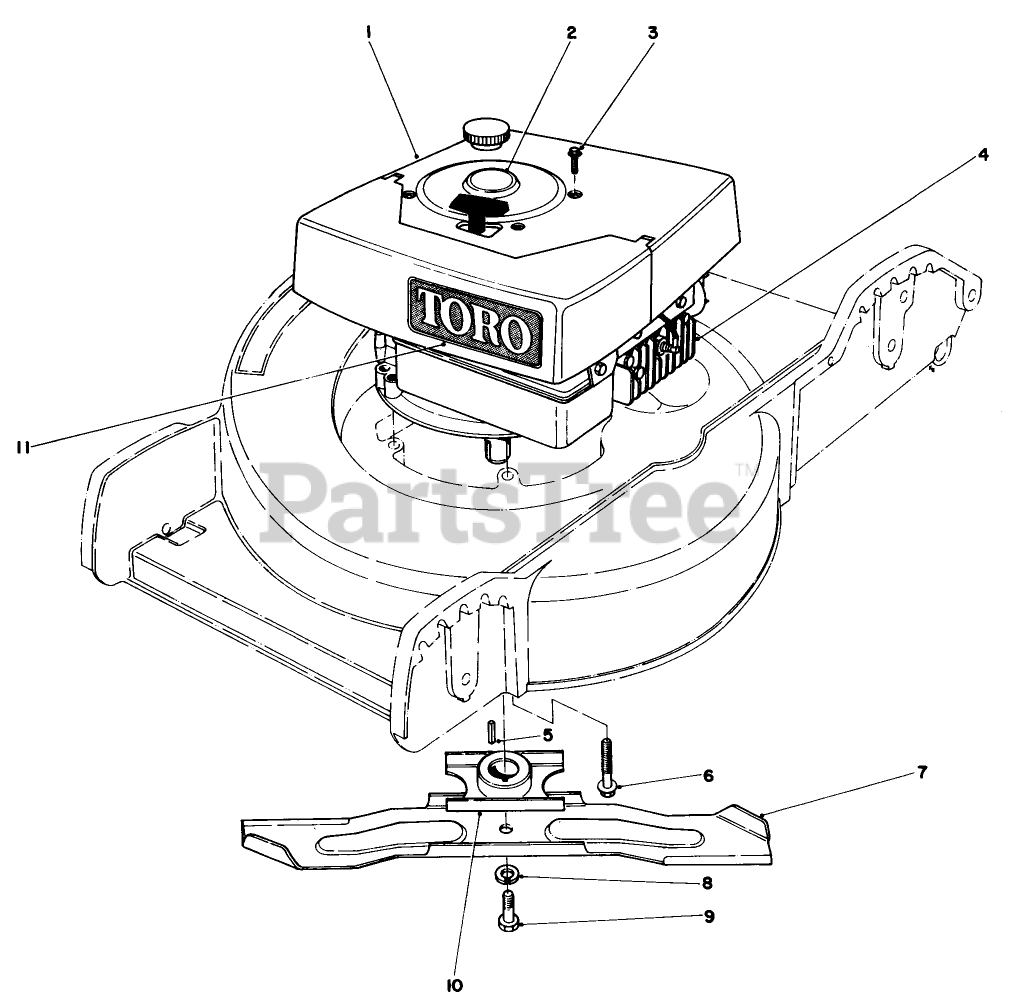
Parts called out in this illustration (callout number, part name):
1	SHROUD
2	Decal-Shroud
3	TAPPING SCREW
4	Engine
5	KEY-SQUARE
6	3/8-16 X 2 CAPSCREW
7	Blade
8	WASHER-LOCK
9	SPECIAL SCREW
10	Blade Retailer
11	Decal Tow
